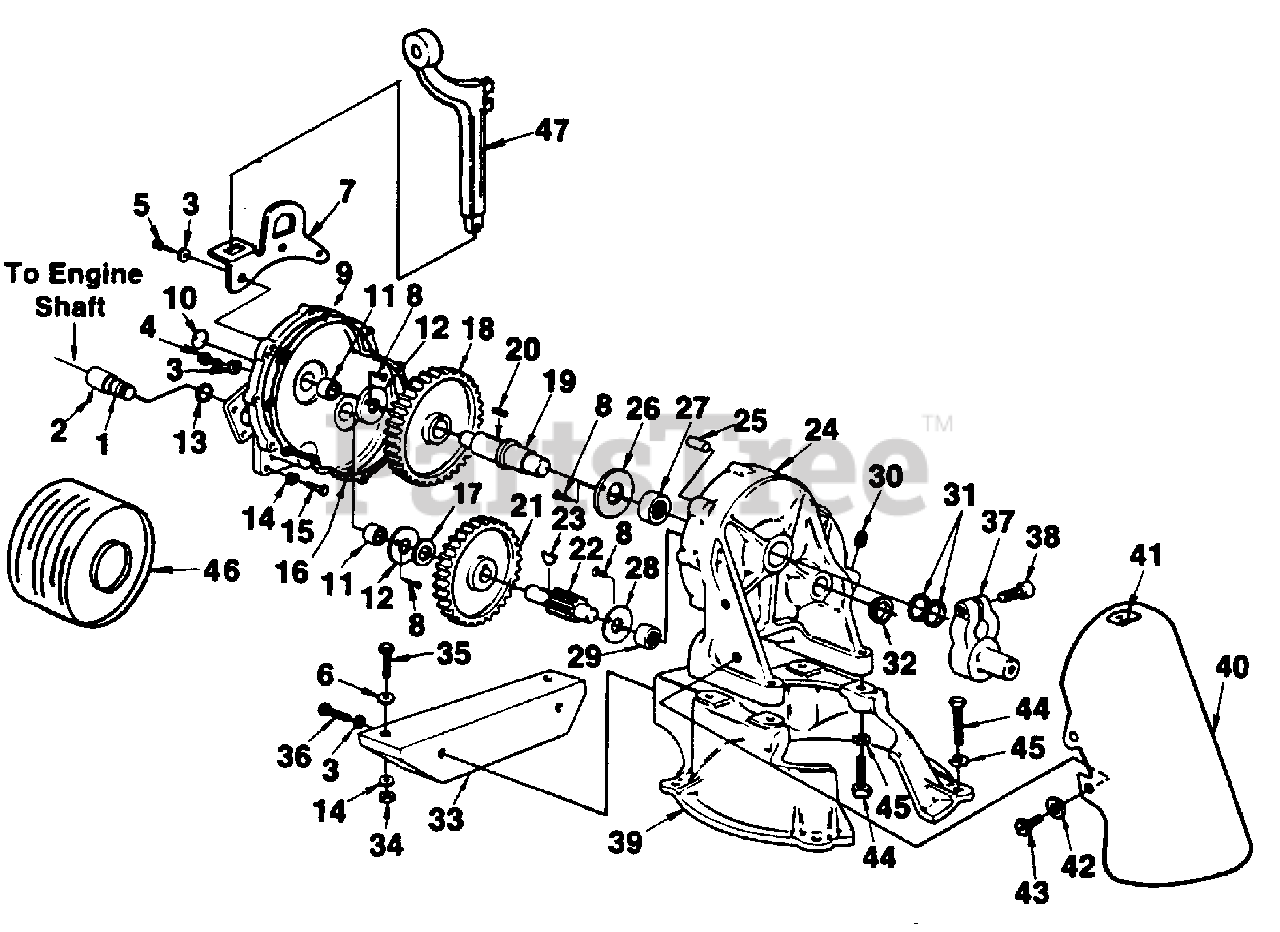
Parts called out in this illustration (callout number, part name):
1	SHAFT- Extension
3	WASHER- Lock (1/4")
4	SCREW- Hex hd. (1/4-20 x 1")
5	SCREW- Hex cap (1/4-20 x 1 1/4")
6	WASHER- Flat (5/16")
7	BRACKET- Lift
8	SCREW- Flat hd. (8-32 x 1/2)
9	GEAR CASE COVER
10	CAP- Bearing
11	BEARING- Needle
12	WASHER- Thrust
13	SEAL- Extension shaft
14	WASHER- Lock (5/16")
16	GASKET- Gear case
18	GEAR- Pump
19	SHAFT- Gear
21	GEAR- Intermediate
24	GEAR CASE ASSEMBLY
25	PIN- Dowel
26	WASHER- Thrust
27	BEARING- Needle
28	WASHER- Thrust
29	BEARING- Needle
30	PLUG- Pipe
31	SEAL- Garlock
32	CAP- Bearing
33	BRACKET- Engine to pump
34	NUT- Hex (5/16-18")
35	SCREW- Cap hex hd. (5/16-18 x 1 3/4")
36	SCREW- Hex hd. (1/4-20 x 3/4")
37	CRANK
38	SCREW- Cap socket hd. (1/2-13 x 1 1/2")
39	BODY- Pump (upper)
40	GUARD- Pump rod
41	DECAL- Grease fitting
42	WASHER- Flat
43	SCREW- Hex hd. (12-24 x 3/8")
44	SCREW- Hex hd. (1/2-13 x 1 3/4")
45	WASHER- Lock (1/2")
46	STRAINER- Suction hose
47	WRENCH- Spanner
